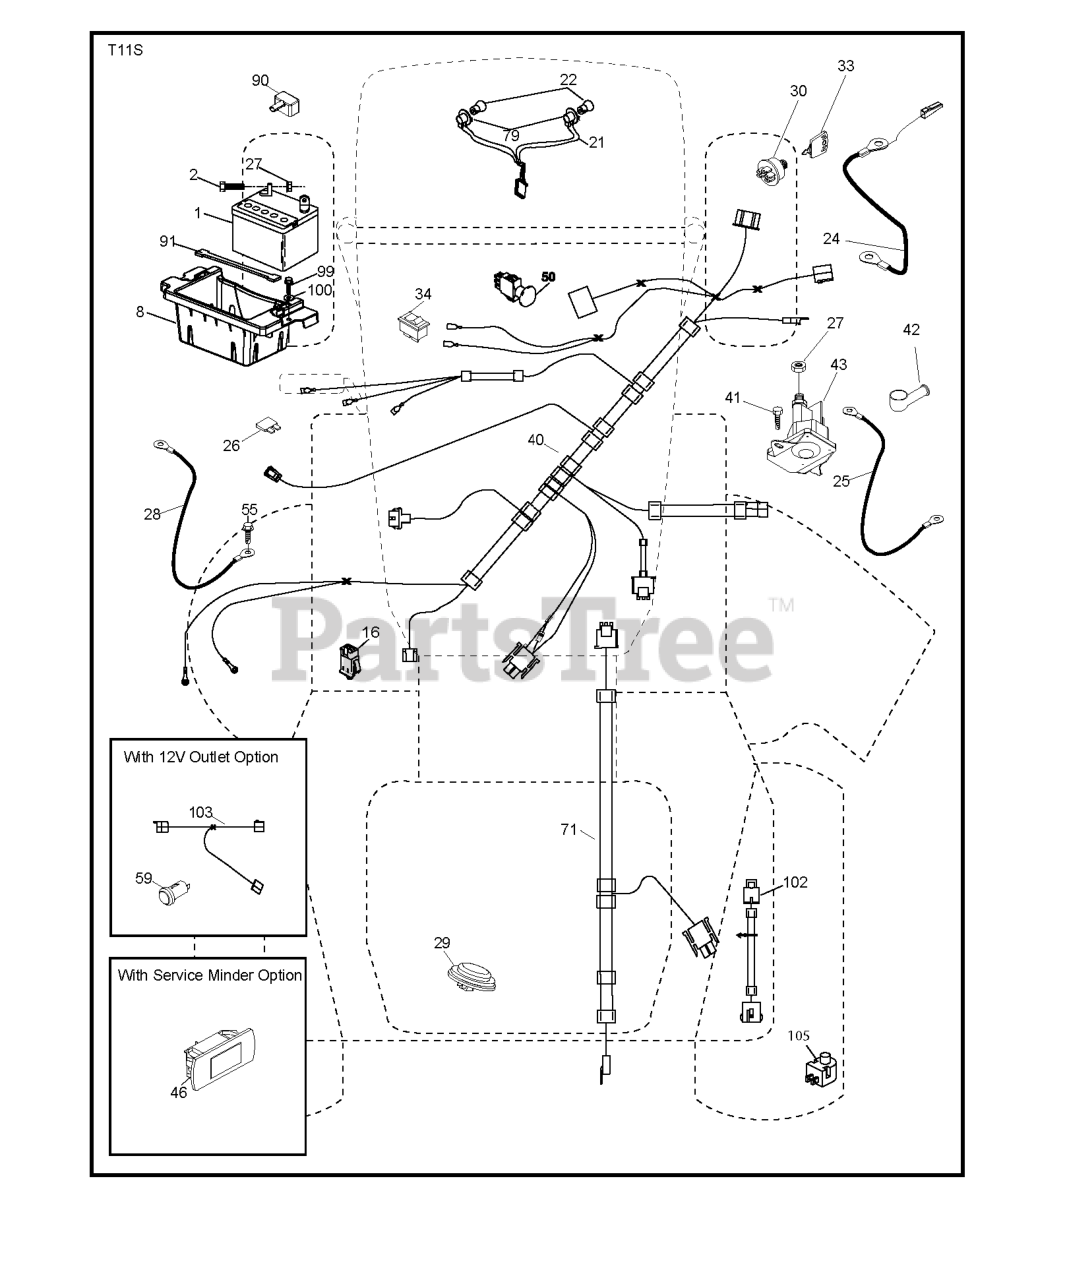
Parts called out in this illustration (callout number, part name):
1	Battery 12 Volt 25 Amp
2	BOLT.HEX.1/4.X.3/4.DICHROMATE
8	BOX.BATTERY.MOUNT.FRONT.LT
16	SWITCH INTERLOOK PUSH-IN
21	HARNESS ASSY LIGHT
24	CABLE.BATT.POS.WIRE.TG.DA SOL
25	CABLE.STARTER.6G.BL/RED.17.5
26	FUSE 20AMP
27	NUT
28	CABLE GROUND 6 GA 21" 90T BLK
29	SWITCH.SEAT.DELTA.OPC.
30	SWITCH.IGN.DELTA.W.LGH.ROS
33	KEY.CHAIN.BLISTER.PACK.GEN.USA
40	HARNESS.IGN.DASH.HUQ/P
41	SCREW
42	TERMINAL COVER
43	SOLENOID.W/BRASS.PLUNGER
46	RP.GUAGE.SRVCMNDR.HRMTR.
50	RP.PTO.SWITCH.8 TERMINAL.BLACK
55	SCREW 5/16"
59	OUTLET.12-VOLT
71	HARNESS-CHASSIS SUB
79	BULB HOLDER ASM.
90	COVER.TERMINAL.BATTERY
91	STRAP.BATTERY.MOUNT.FRONT(2 2)
99	SCREW HEXWSHR 1/4-20X3/4
100	WASHER
102	HARNESS PIGTAIL PCH TEX ROS
103	HARNESS PIGTAIL 12V OUTLET
105	REVERSE SWITCH
